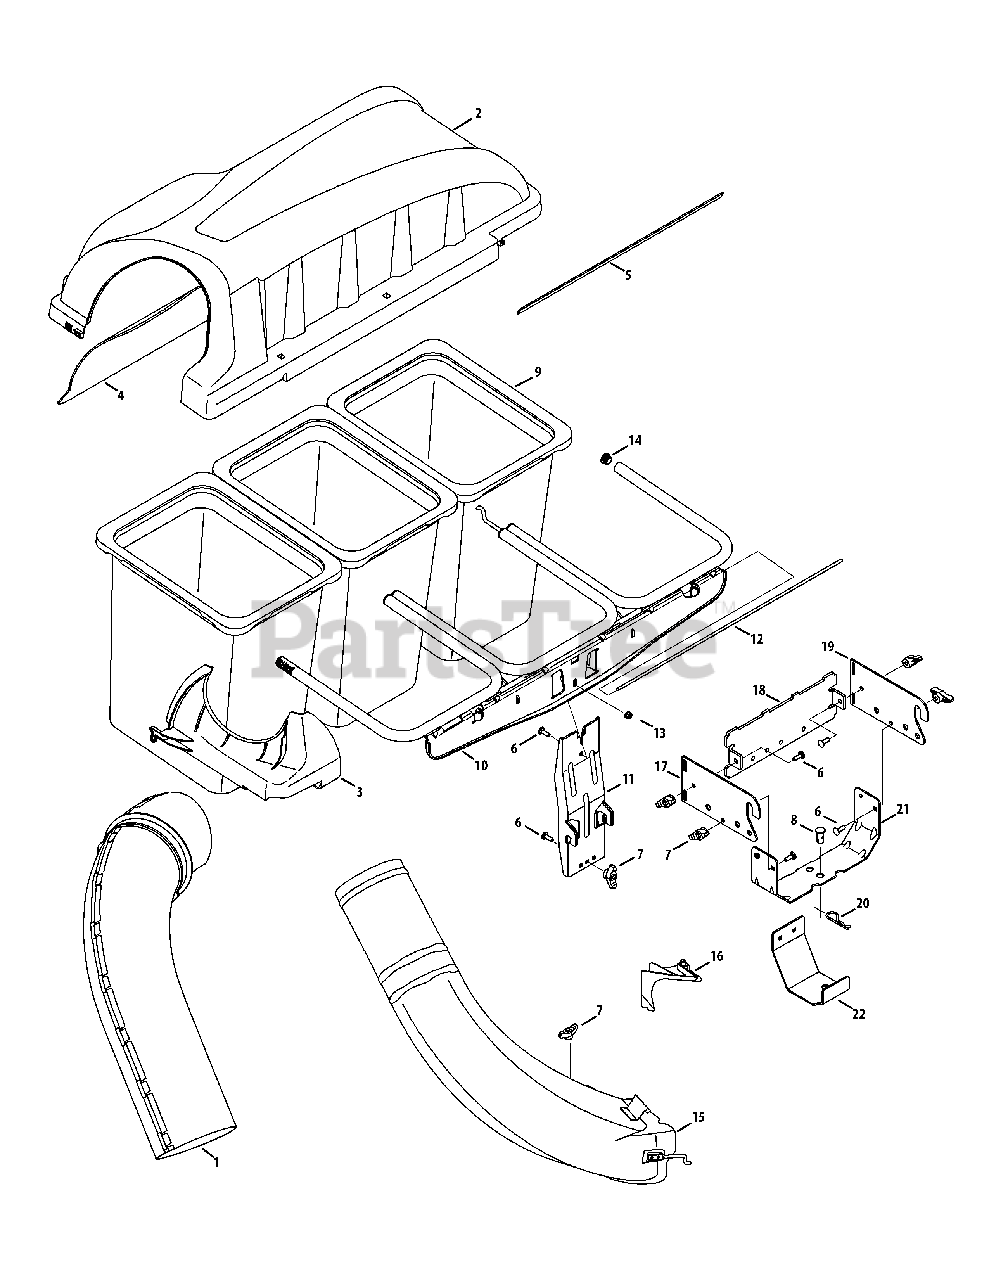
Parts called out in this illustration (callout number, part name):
1	Upper Chute Assembly
2	Triple Bagger Cover Assembly
3	Upper Chute Support
4	Bagger Cover Screen
5	Adhesive Foam Strip
6	Carriage Screw, 5/16-18 x 1.00"
7	Wing Knob, 5/16-18
8	Clevis Pin, .62" Dia.
9	Grass-bag Assembly
10	Triple Bag Support Assembly
11	Vertical Support Bracket
12	Cover Hinge Pin
13	Flange Lock Nut, 5/16-18
15	Discharge Chute Elbow, 50/54" Deck
16	Chute Adapter, 50-54" Decks
17	Hitch Bracket, RH
18	Universal Rear Attachment Bracket
19	Hitch Bracket, LH
20	Clevis Pin, .62 Dia.
21	Universal Bracket Support
